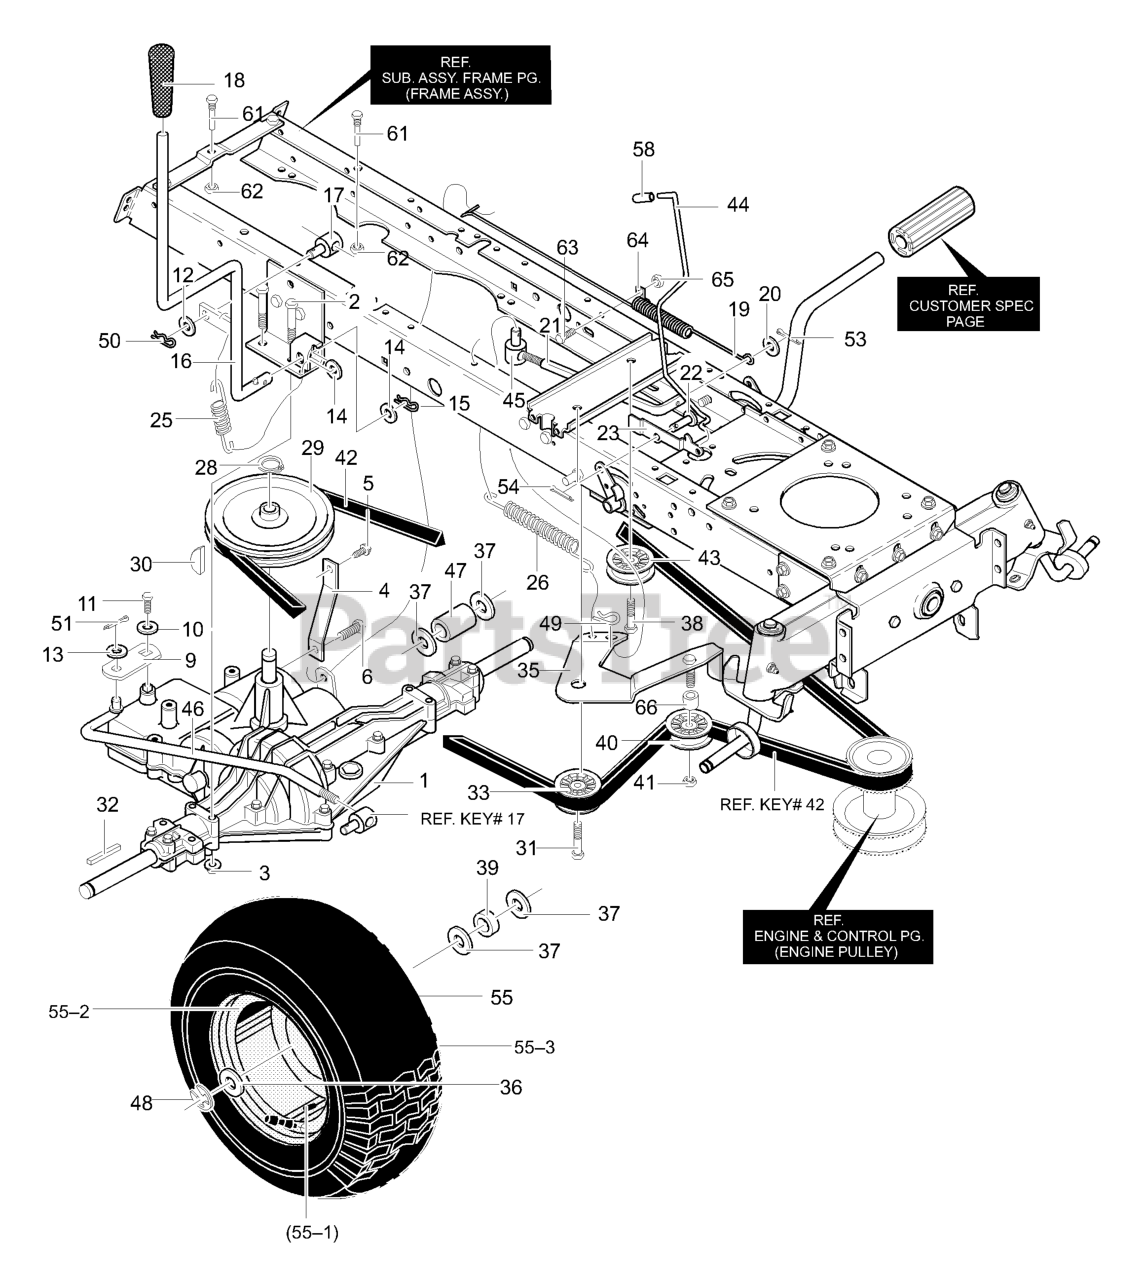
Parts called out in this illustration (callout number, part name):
1	Transaxle, MST206 **
2	Screw, 5/16-18 x 2.50
3	Nut, 5/16-18
4	Bracket, Stabilizer
5	Screw, 5/16-18 x 0.75
6	Screw, 5/16-18 x 0.75
9	Bracket, Shift
10	Washer, Transaxle
11	Screw, 1/4-28x.750
12	Washer, Flat
13	Washer
14	Flatwasher
15	Hair Pin
16	Shift Lever
17	Nut, Adjust
19	Spring, Brake
20	Washer, Flat
21	Rod, Clutch
22	Pin, Clevis
23	Latch, Park Brake
26	Spring, Tension
28	Ring, Ret
29	Pulley, 9.0 ODV4L
30	Key, Hi Pro 606
31	Screw, 3/8-16 x 1.25
32	Key, Square
33	Pulley, Idler
35	Assy, Idler Arm Traction
36	Washer, Flat
37	Washer, Flat
38	Screw, 3/8-16 x 1.25
40	Pulley, Idler
41	Nut, 3/8-16
42	Belt, V 4L 114.12
43	Pulley, Idler
44	Park Brake control Rod
45	Nut, 5/16-18 Adjusting
46	Rod, Shift Link
47	Spacer
48	E-Ring
49	Pin, Hair
50	Pin, Hair
51	Pin, Cotter
53	Pin, Cotter
54	Pin, Cotter
55	Tire & Rim
55-1	Valve Stem
58	Cap, Dump
61	Screw Guide
62	Nut, 1/4-20
63	Screw, 1/4-20x.50
64	Retainer
65	Nut, 1/4-20
66	Spacer 1/2 to 17MM
